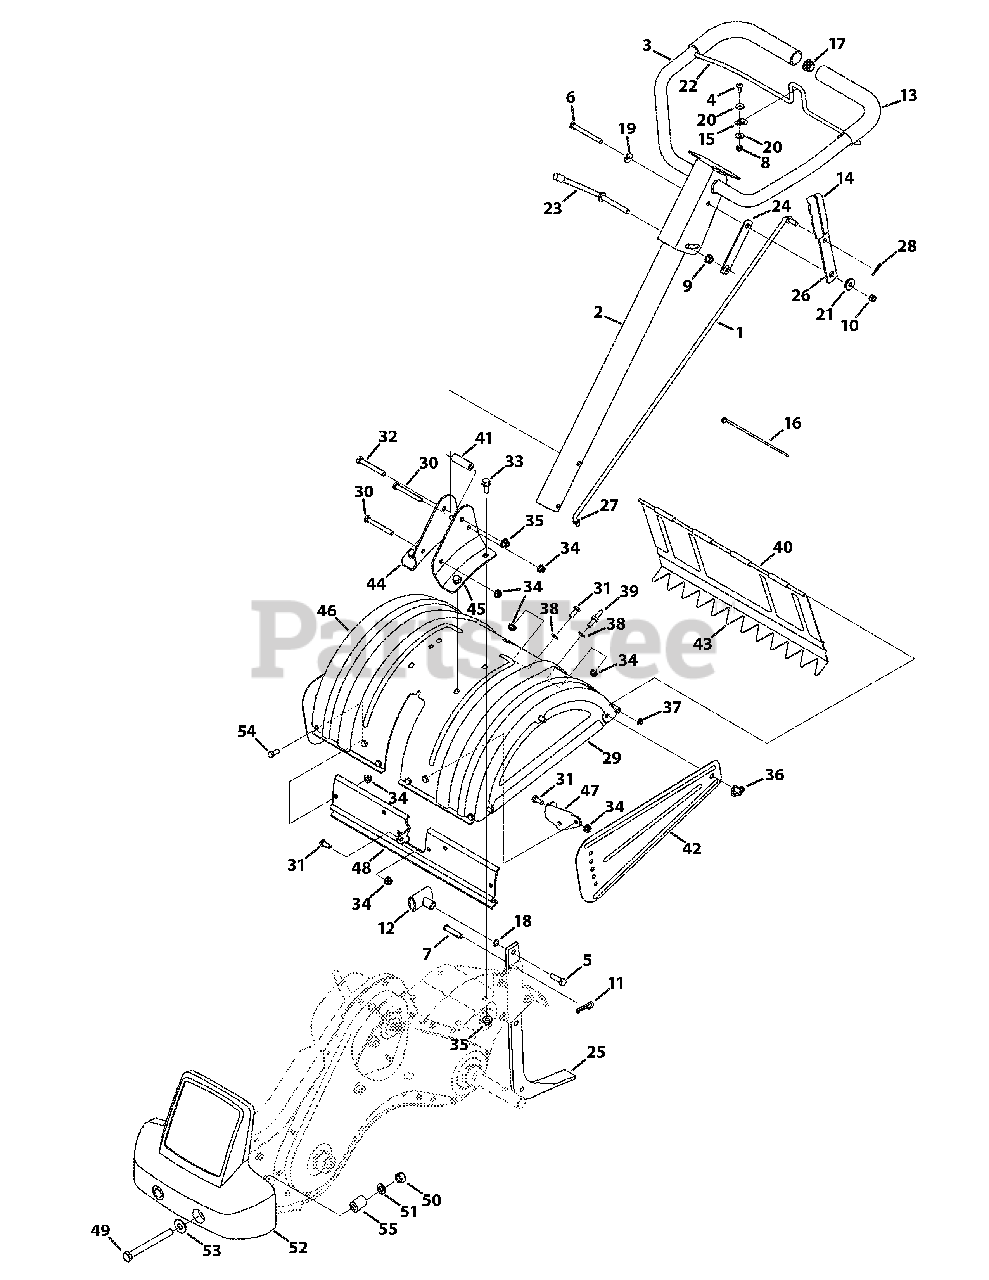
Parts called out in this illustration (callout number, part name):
1	Shift Rod
2	Lower Handle Tube Assembly
3	Upper Handle Assembly
4	Screw, 1/4-20 x 0.625
5	Hex Head Screw, 3/8-16:1.25
6	Hex Head Screw, 5/16-18 x 3.25
7	Clevis Pin, .375 X 1.75
8	Hexlock Nut, 1/4-20
9	Flangelock Nut, 3/8-24
10	Hexlock Nut, 5/16-18
11	Cotter Pin, .125 X 1.75 Internal
12	Small Tee Knob
13	Foam Grip, .970 x 11.0
14	Grip, .1875 x 1.00
15	Clamp, 5/16
16	Cable Tie, 8.5 LG
17	End Plug
18	Washer, Flat, .385 x .620 x .033
19	Washer, Bell, .340 x .872 x .060
20	Washer, Flat, .260 x .720 x .060
21	Spacer, .50 x .190 x .360 LG
22	Clutch Bail
23	Handle Adjustment Crank
24	Hex Nut Retainer Bracket
25	Tiller Depth Control
26	Shaft Rod Lever
27	Washer, .33 ID x .87 OD x .125
28	Cotter Pin, .072 x 1.12 LG
29	End Cover Assembly
30	Hex Head Screw, 5/16-18 x 2.75
31	Hex Head Screw, 5/16-18 x .75
32	Hex Head Screw, 3/8-16 x 2.75
33	Hex Head Flange, 3/8-16 x .875
34	Flangelock Nut, 5/16-18
35	Flangelock Nut, 3/8-16
36	Wing Nut, 5/16-18 W/ Bell Washer
37	Speed Nut Cap, 1/4 ROD
38	Washer, Flat, .344 x .62 x .033
39	Screw, Hex, 5/16-18 x .75
40	Tiller Flap Rod
41	Spacer, .322 x .625 x 2.00
42	Side Shield
43	Rear Tine Shield
44	RH Handle Mount Bracket
45	LH Handle Mount Bracket
46	Tine Shield
47	FRT Tine Shield Bracket
48	FRT Tine Shield Spacer Bracket
49	Hex Head Screw, 1/2-20 x 5.50
50	Hex Nut, 1/2-20
51	Washer, Lock, 1/2
52	Counterweight
53	Washer, Flat, 1/2 x 1.25 x .100
54	Hex Head Screw, 5/16-18 x 1.00
55	Hub, .636 ID x 1.00 OD x .94
